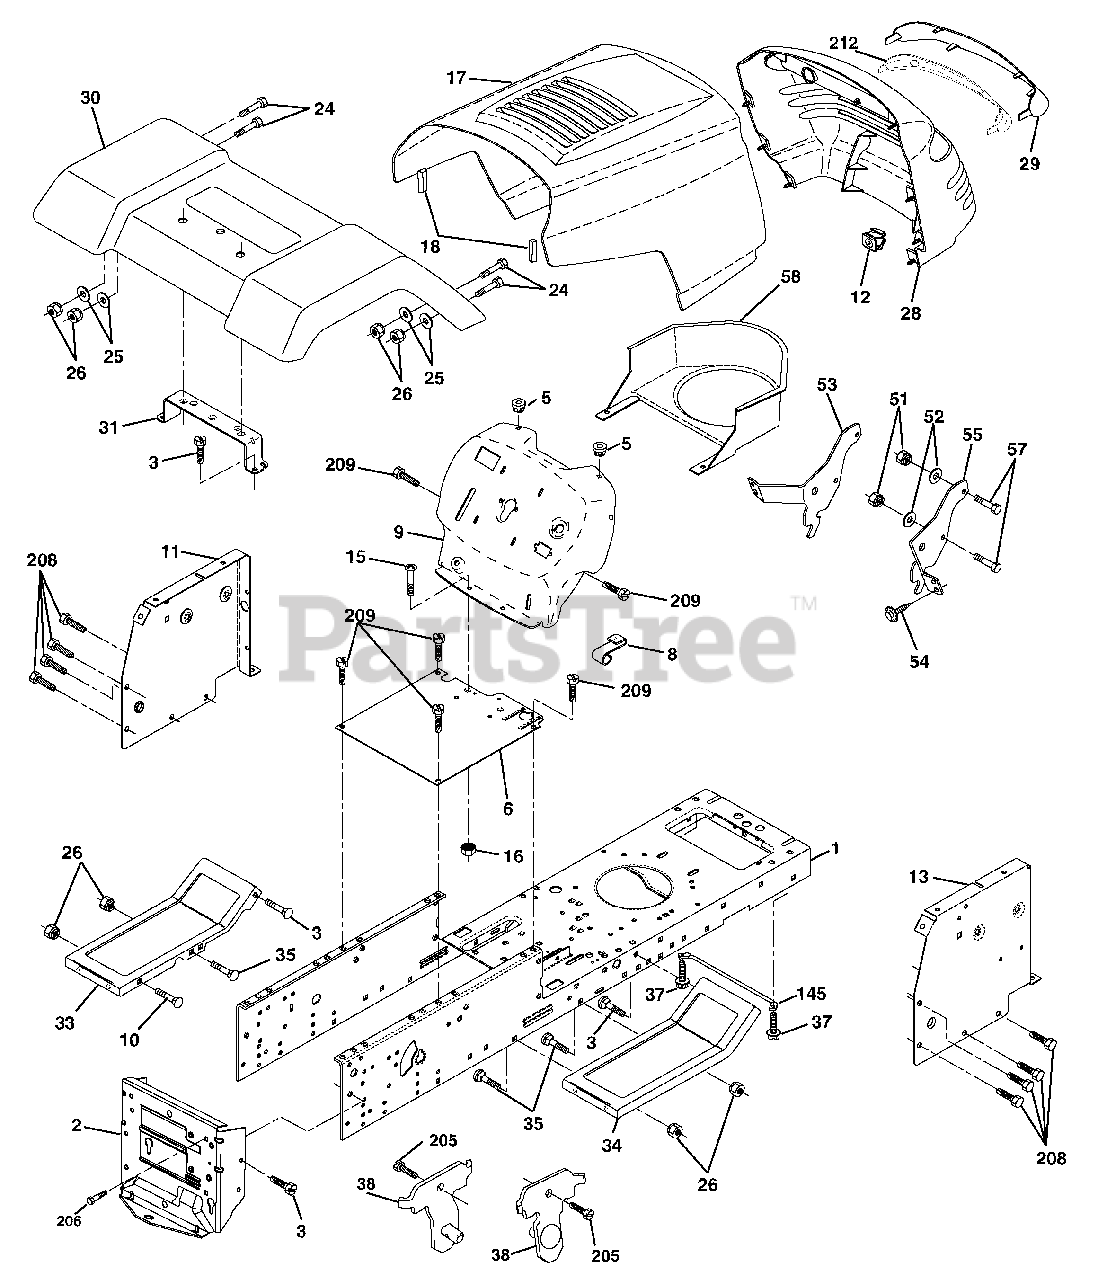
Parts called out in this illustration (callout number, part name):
1	Chassis
2	Drawbar
3	Screw 3/8-16 x 3/4
5	Bumper Hood/Dash
6	Saddle Flat Lt
8	Clip Retainer Slide-On
9	Dash
10	Bolt Rd Hd Sqnk. 3/8-16 Unc x 1
11	Panel Asm. Dash Lh
12	Clip Tinnerman Grile P/L
15	Screw Mach Trhd 5/16-18 Unc x 3/4
16	Nut Keps 5/16-18 Unc
17	Hood
18	Bumper Hood
24	Bolt Fin Hex 3/8-16 Unc x 1 Gr. 5
25	Washer 13/32 x 13/16 x 12 Ga.
26	Nut Lock Hex w/Insert 3/8-16 UNC
28	Grill/Lens Asm
29	Lens Grille Private label
31	Bracket Fender
33	Footrest
34	Footrest
35	Bolt Rd Hd Sht. Sqnk. 3/8-16 x 3/4
37	Screw Thdrol 5/16-18 x 1/2 Tyt
38	Bracket Asm. Pivot Mower Rear
51	Nut Lock Hex W/Ins. 1/4-20
52	Washer 9/32 x 7/8 x 16 Ga.
53	Bracket Grille LH
54	Screw Hex Wshd 8-18 x 7/8
55	Bracket, Grille RH
57	Bolt Fin Hex 1/4-20 x .75
58	Air Duct Private Label
145	Rod Pivot Chassis/Hood
205	Screw Thdrol 3/8-16 x 1/2
206	Bolt shoulder 5/16-18
208	Screw Thdrol 3/8-16 x 1/2
209	Screw Hex Wsh Thdrol 3/8-16
212	Insert Lens Reflector
